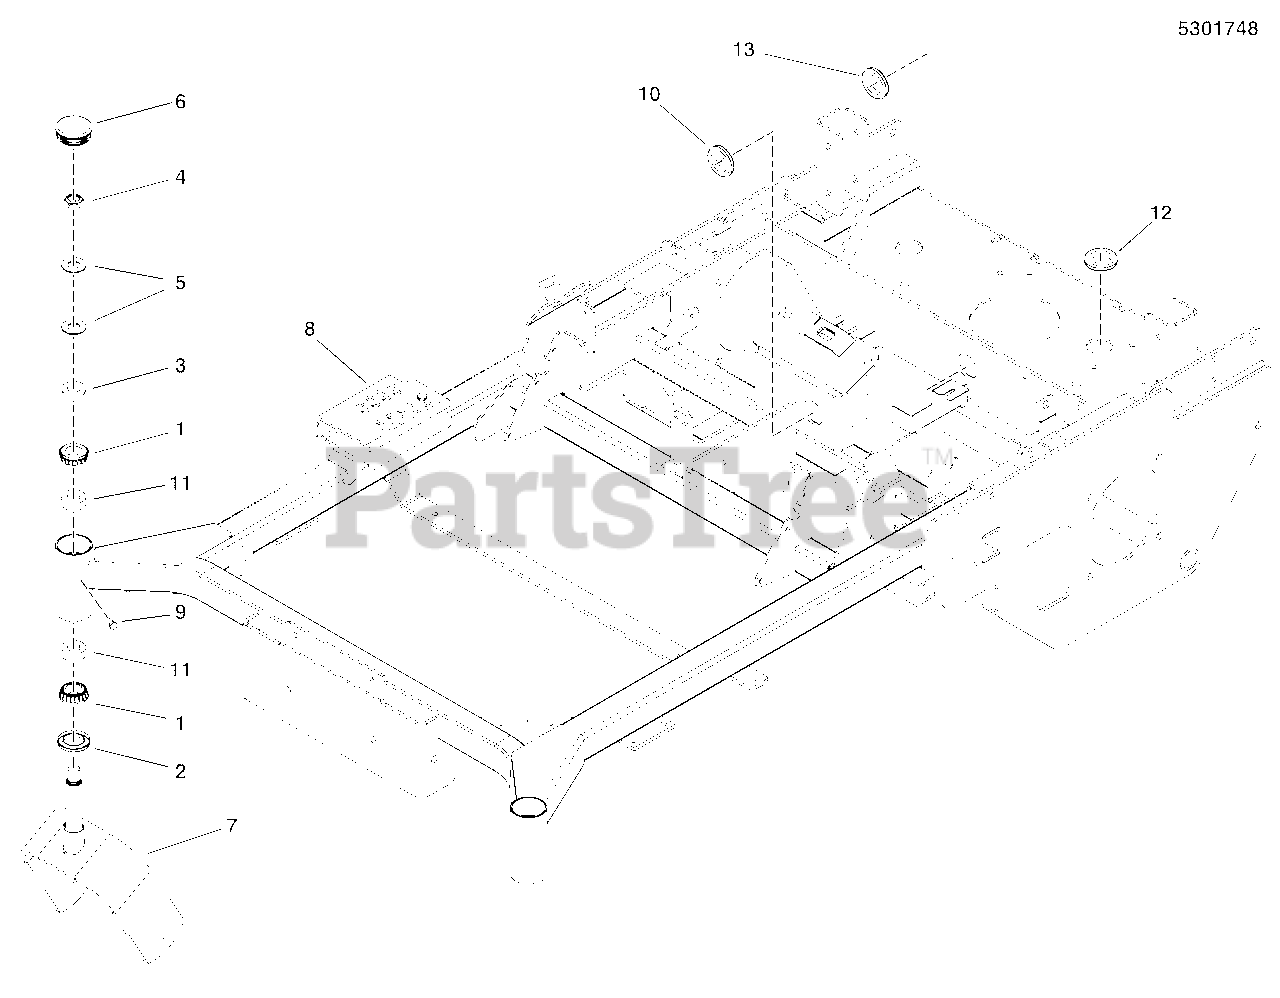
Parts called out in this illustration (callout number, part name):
1	BEARING, TAPERED ROLLER, 1"
2	SEAL, GREASE
3	WASHER, 3/4 SAE
4	NUT, 3/4-16, HEX JAM NYLON LOCK
5	WASHER, BELLEVILLE - 1.500 X .755
6	CAP, GREASE, LOW PROFILE
7	WELD, CASTER YOKE - RED
9	BOLT, 1/4-28 X 1/2, GD5 YZ
10	GROMMET, 1-1/4"
11	CUP, BEARING (SV)
12	GROMMET, 7/8"
13	GROMMET, 2" ID
